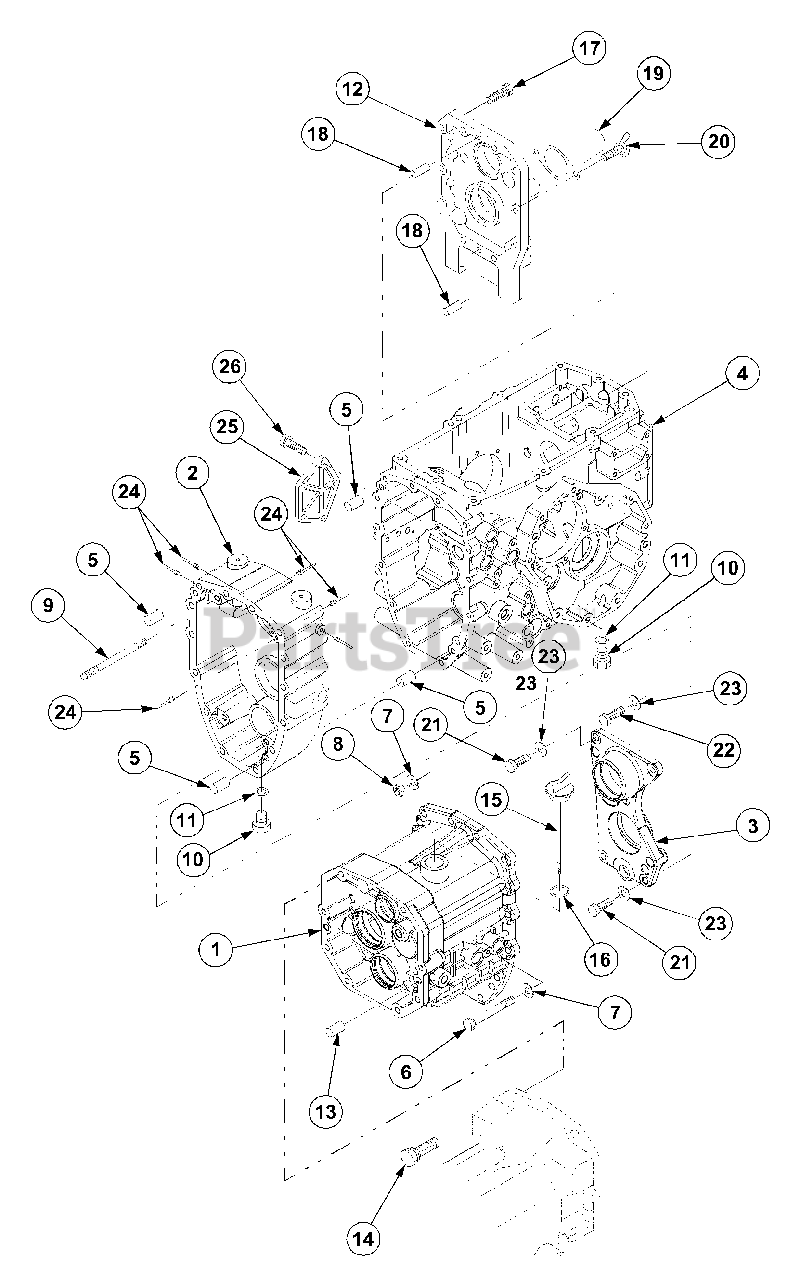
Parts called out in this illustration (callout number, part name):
1	Housing, Transmission
2	Holder, Bearing
3	Cover - Mod. 7530
4	Housing, Diff
7	Washer, Spring
14	Bolt, w/Washer
17	Bolt, w/Washer
26	Bolt, w/Washer
